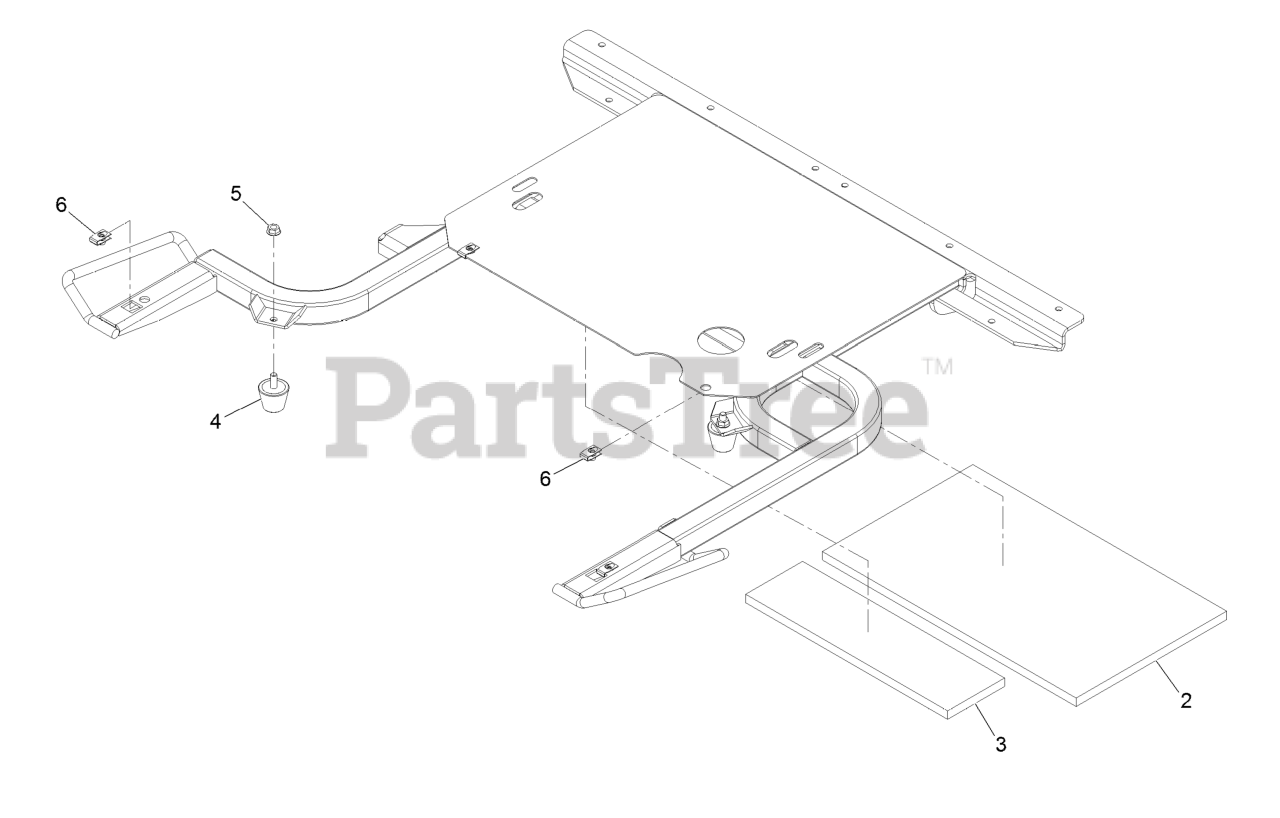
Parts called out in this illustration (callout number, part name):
2	INSULATION-FOAM PAD, REAR
3	INSULATION-FOAM PAD, FRON
4	BUMPER-RUBBER
6	Nut-Retainer-Panel 1/4-20
